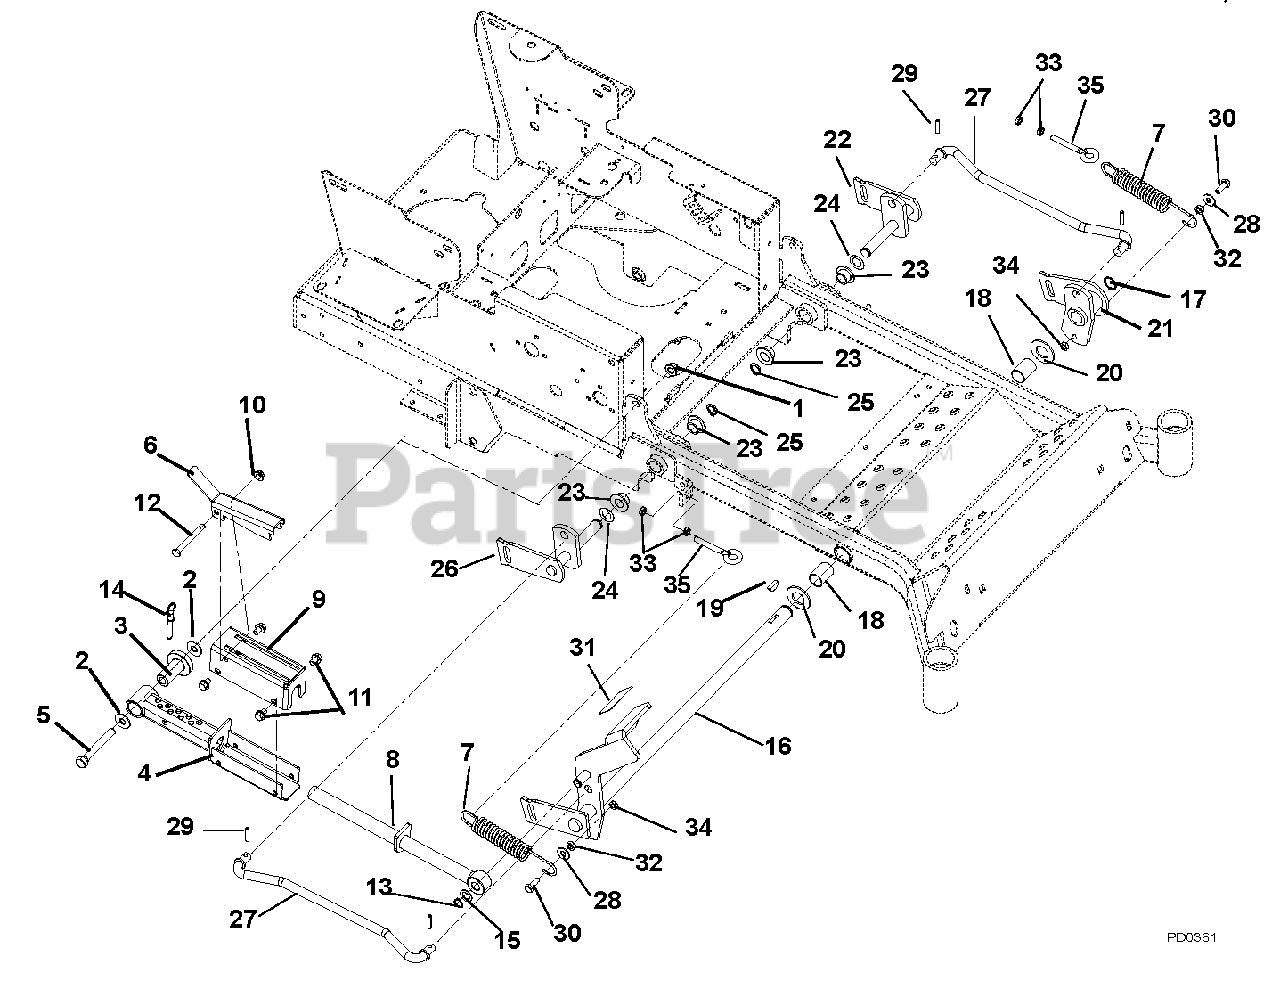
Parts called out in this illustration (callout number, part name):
1	Nut, Locking Top Flange .50-13
2	Washer, Flat Steel .531 x 1.25 x .10
3	Bearing, Pedestal
4	Weldment, Mechanical Lift
5	Bolt, Hex .50-13 x 3.75 Grade 5
6	Lock-Up, Mechanical Lift
7	Spring, Tension .162 x 1.25 x 8.25 Weldment 25
8	Weldment, Mechanical Lift Shaft
9	Weldment, Mechanical Lift Cover
10	Nut, Nyloc Flange 3/8-16
11	Screw, Tapping .38-16 x .50 Hex Washer Head
12	Bolt, Hex .38-16 x 3.25 Grade 5
13	Ring, Retaining External .625 x .050
14	Pin, Spring Ball .375 O.D. x 1.50
15	Washer, Flat Steel .630 x .005 x .062
16	Weldment, Foot Operated Deck Lift
17	Ring, Retaining External 1.00 x .078
18	Bushing 1.00 ID x 1.125 OD x 1.50
19	Key, Woodruff .25 x 1.00
20	Washer, Flat Steel 1.062 x 2.0 x .134
21	Weldment, Left Hand Mower Lift Arm
22	Weldment, Left Hand Rear Mower Lift Arm
23	Bushing, Flange Nylon .762 x 1.0 x .580 x 1.48
24	Washer, Hardened Steel .758 x 1.23 x .031
25	Ring, Retaining External .689 x .077
26	Weldment, Right Hand Rear Mower Lift Arm
27	Rod, Lift Assist
28	Washer, Flat Steel .438 x 1.00 x .083
29	Pin, Roll .25 x 1.25 Stainless Steel
30	Bolt, Hex .38-16 x 1.00 Grade 5
31	Grip, Pedal
32	Bushing, Sleeve .377 x .624 x .235
33	Nut, Hex-Jam .375-16
34	Nut, Locking-Jam-Center .375-16
35	Bolt, Eye .375-16 x 2.50
